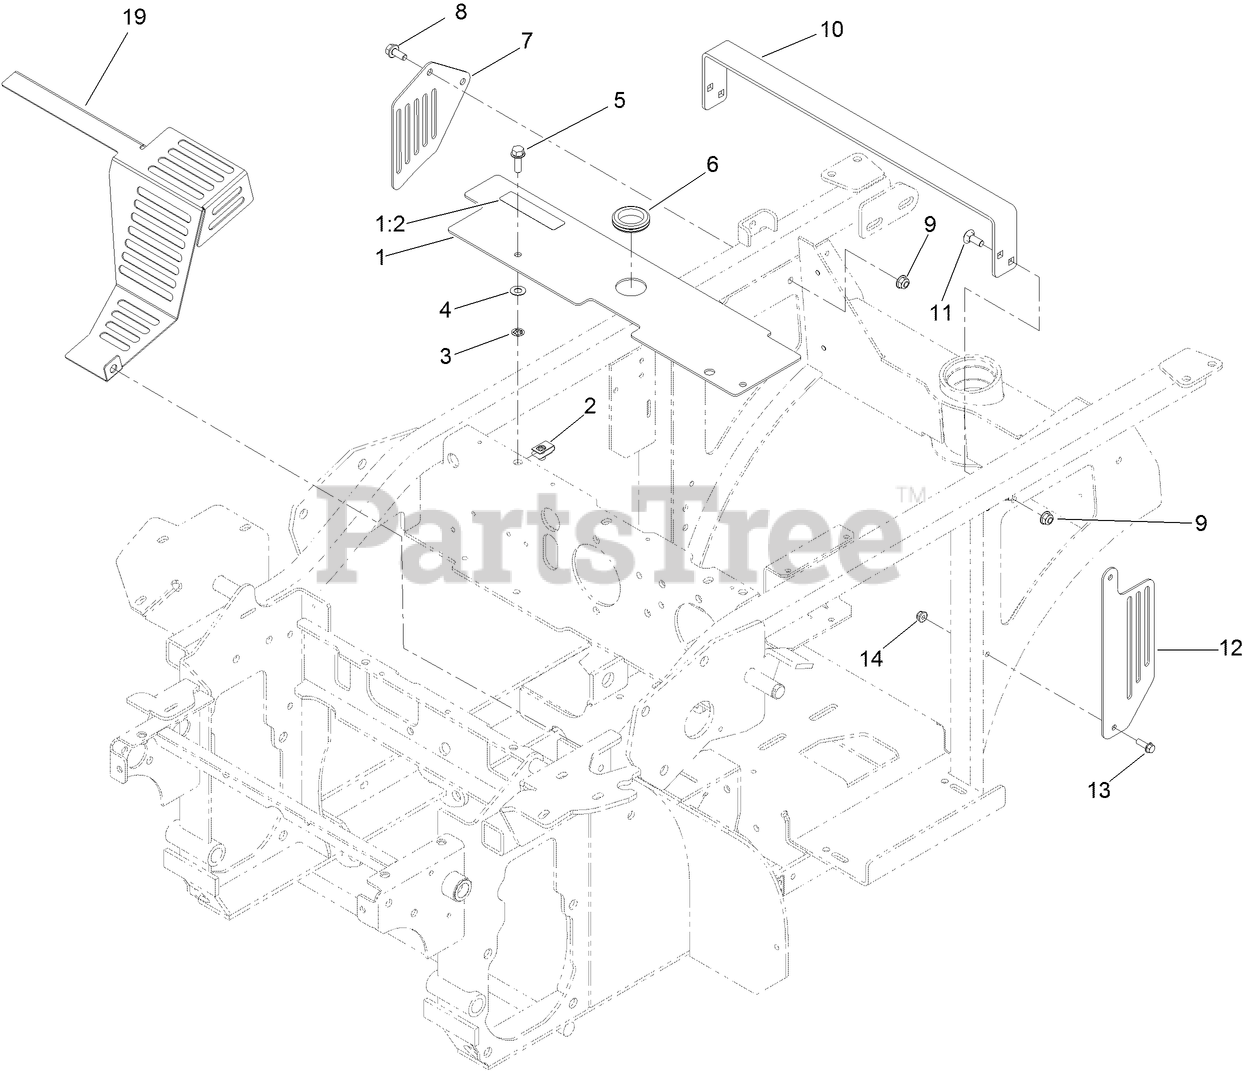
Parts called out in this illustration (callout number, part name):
1	PUMP GUARD ASM
1:2	DECAL-WARNING
2	NUT-CLIP, U
3	NUT-PUSH
4	WASHER-THRUST
5	SCREW-HHF
6	GROMMET-RUBBER
7	GUARD-MUFFLER, RH
8	SCREW-HHF
9	NUT-HF, NI
10	GUARD-MUFFLER, TOP
11	SCREW-CARR
12	GUARD-MUFFLER, LH
13	SCREW-HWH
14	NUT-HF
19	SHIELD-HEAT
